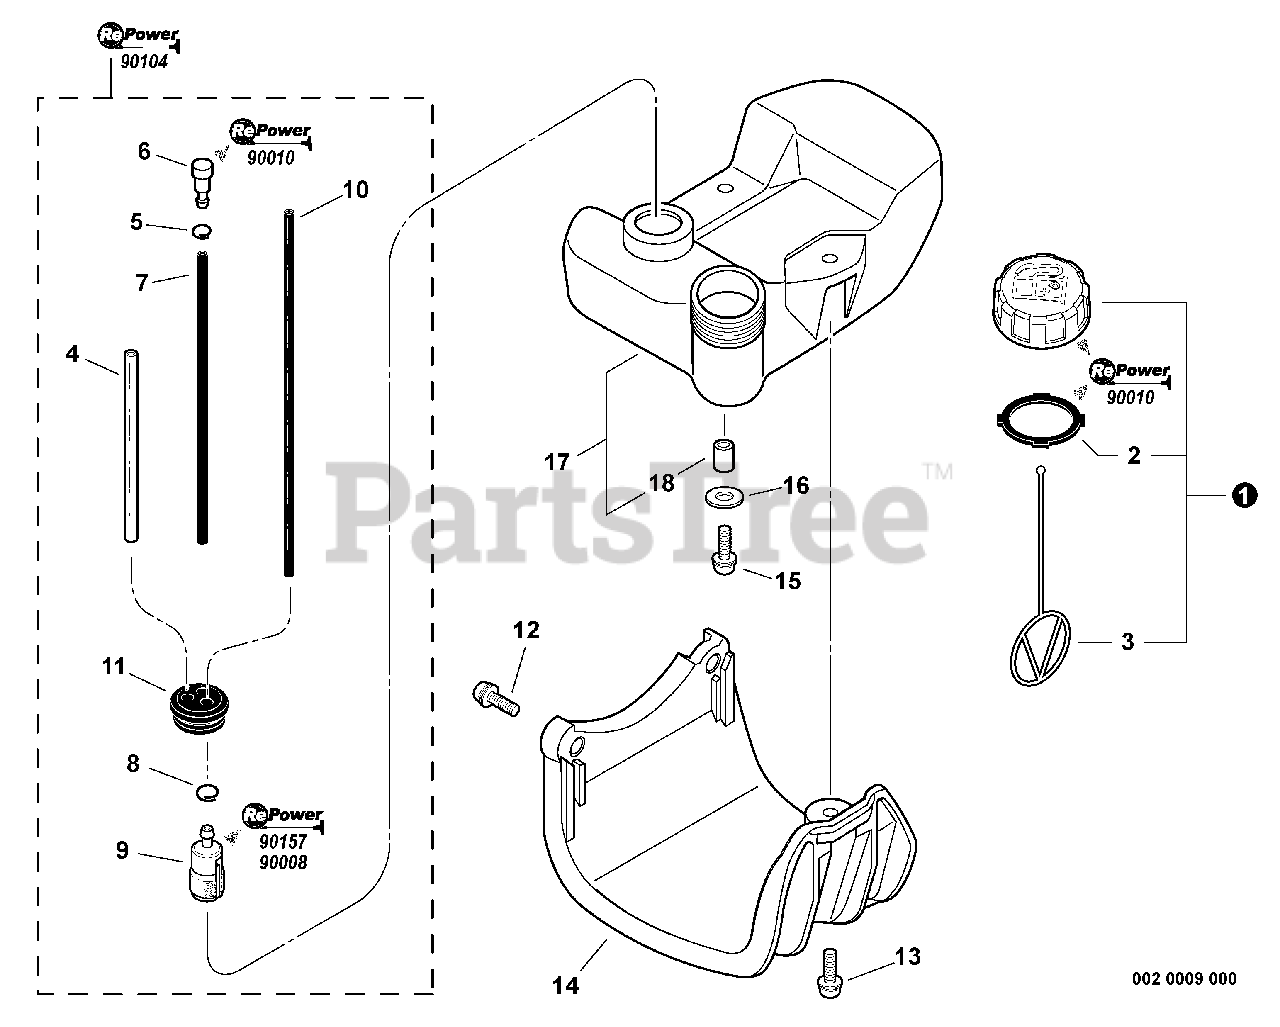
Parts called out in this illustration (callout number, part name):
1	CAP ASSY, FUEL
2	GASKET, FUEL CAP
3	CONNECTOR, CAP L= 100 MM
4	PIPE, FUEL 3×6×80 CLEAR
5	CLIP Ø6.5 MM
6	VENT ASSY
7	PIPE 3×6×115 BLACK
8	CLIP Ø6.5 MM
9	FILTER, FUEL
10	PIPE, FUEL 3×6×170
11	GROMMET, FUEL
12	BOLT 5×22
13	SCREW 5×20
14	GUARD, FUEL TANK
15	BOLT 5×16
16	WASHER 5.5×12×0.8
17	TANK, FUEL
18	SPACER 6.2×7.8×6
19	FILTER KIT - REPOWER
20	CAP/VENT KIT - REPOWER
21	FUEL SYSTEM KIT
22	TUNE-UP KIT
